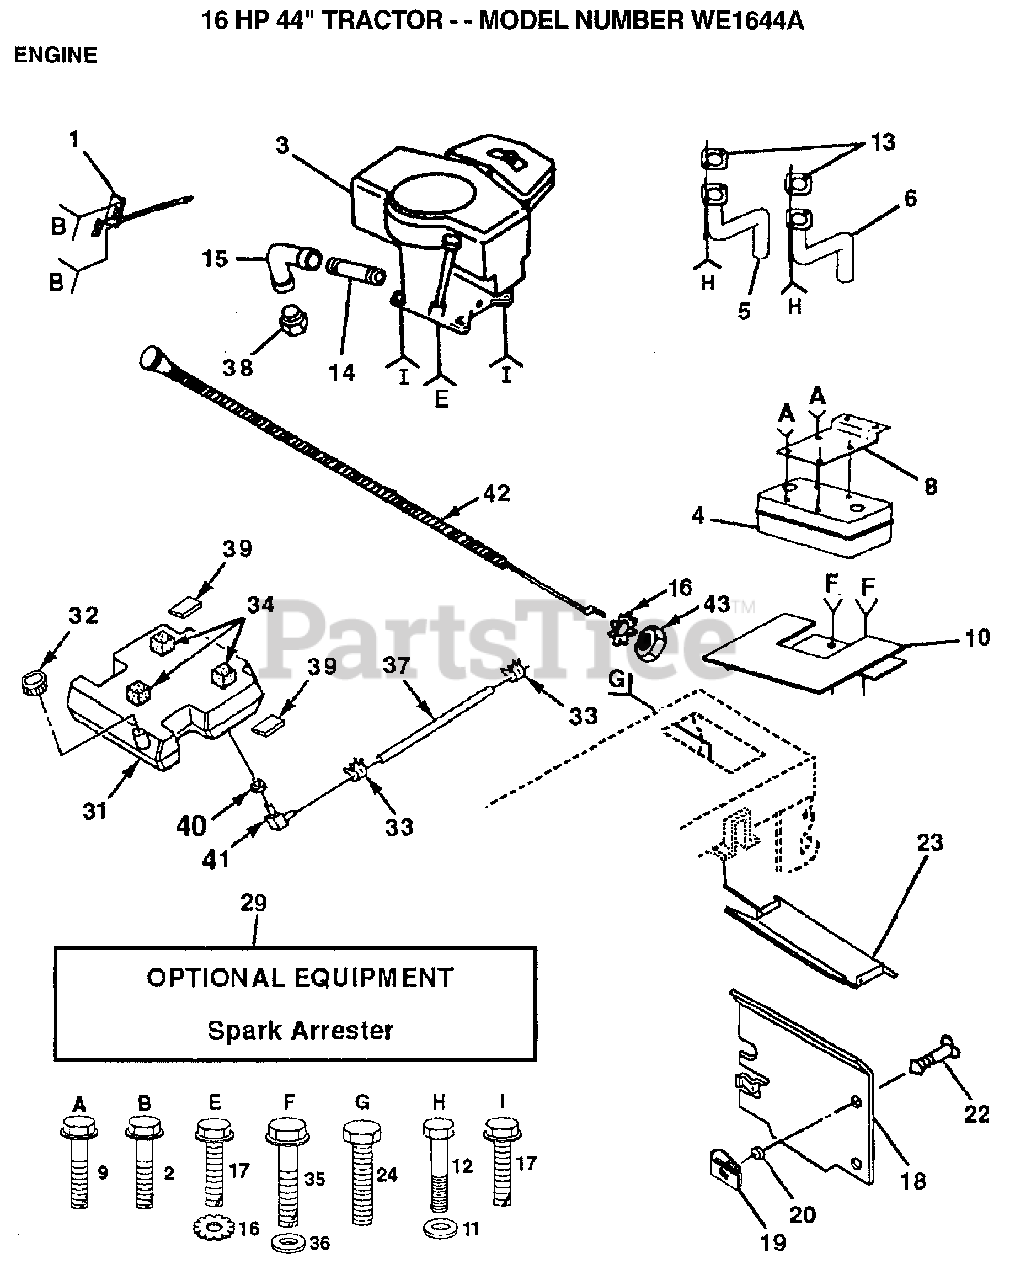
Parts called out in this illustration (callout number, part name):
1	CONTROL.THROTTL
2	SCREW LT
3	ENGINE, B&S
5	EXHAUST ASM LH
8	BRACKET MUFFLER
9	SCREW ST
10	SHIELD HEAT LT
11	LOCKWASHER
14	PIPE NIPPLE LT
15	ELBOW
16	LOCKWASHER
17	SCREW LT
18	HEAT SHIELD
19	RECEPTACLE LT
20	RETAINER LT
22	STUD.1/4.TURN
23	HEAT SHIELD
24	SCREW
32	CAP ASM FUEL
33	HOSE CLAMP
34	PAD-SPACER LT
35	SCREW
36	WASHER
37	FUEL LINE T
38	DECAL, OPEI
39	PAD IDLER TI
40	BUSHING OUTLET T
41	STEM.TANK.FUEL
42	CHOKE CONTROL
